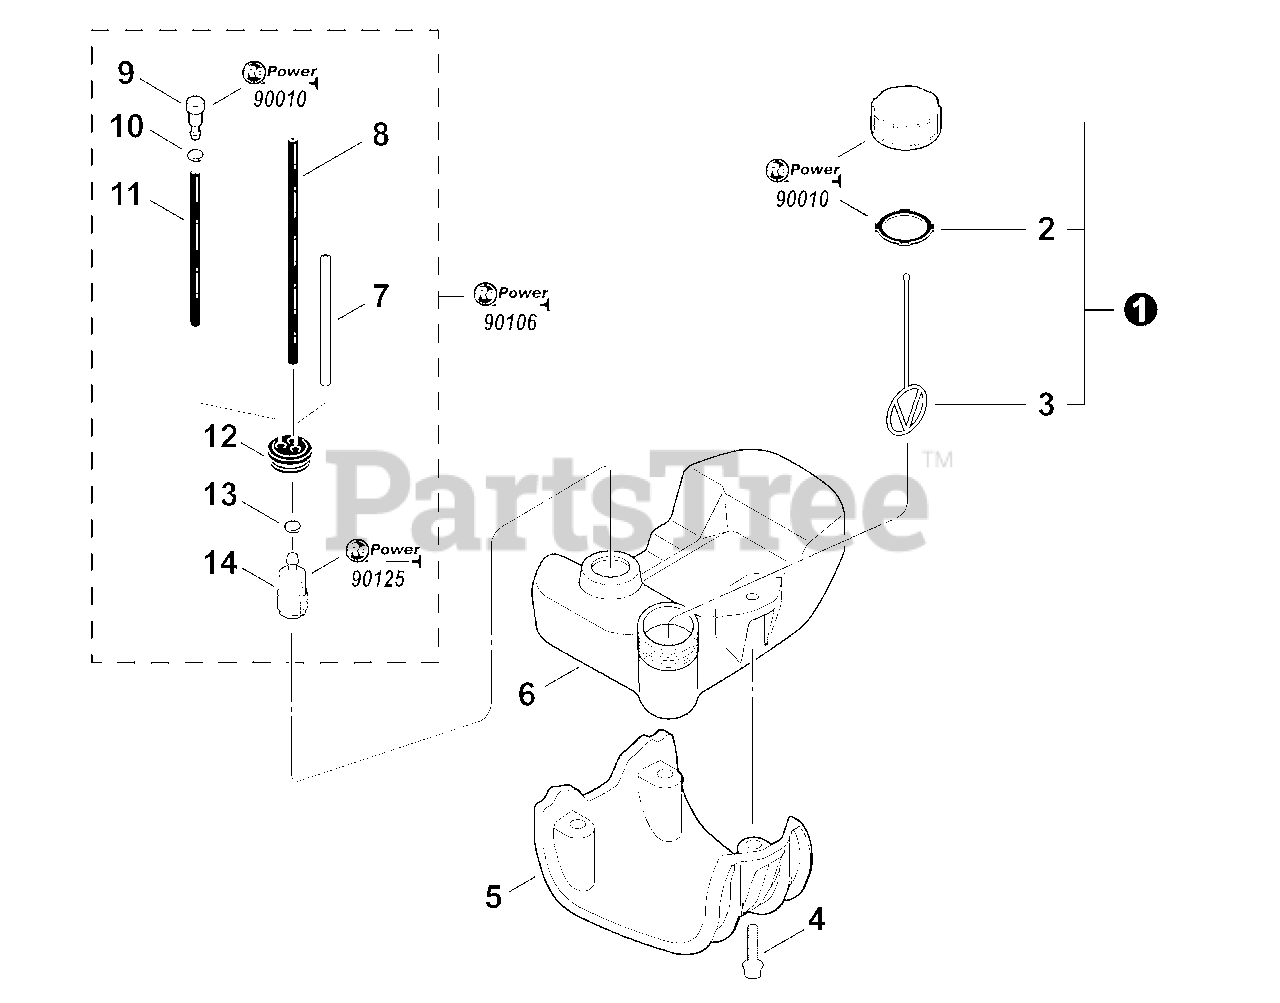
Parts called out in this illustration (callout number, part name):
1	CAP ASY - ORANGE
2	GASKET
3	CONNECTOR, CAP
4	SCREW - 5×20
5	GUARD, FUEL TANK
6	TANK, FUEL
7	PIPE - 3×6×80 -- CLEAR
8	PIPE - 3×5×195 -- BLACK
9	VENT, FUEL TANK
10	CLIP - 6.5
11	PIPE - 3×6×115 -- BLACK
12	GROMMET
13	CLIP - 6
14	FILTER, FUEL
